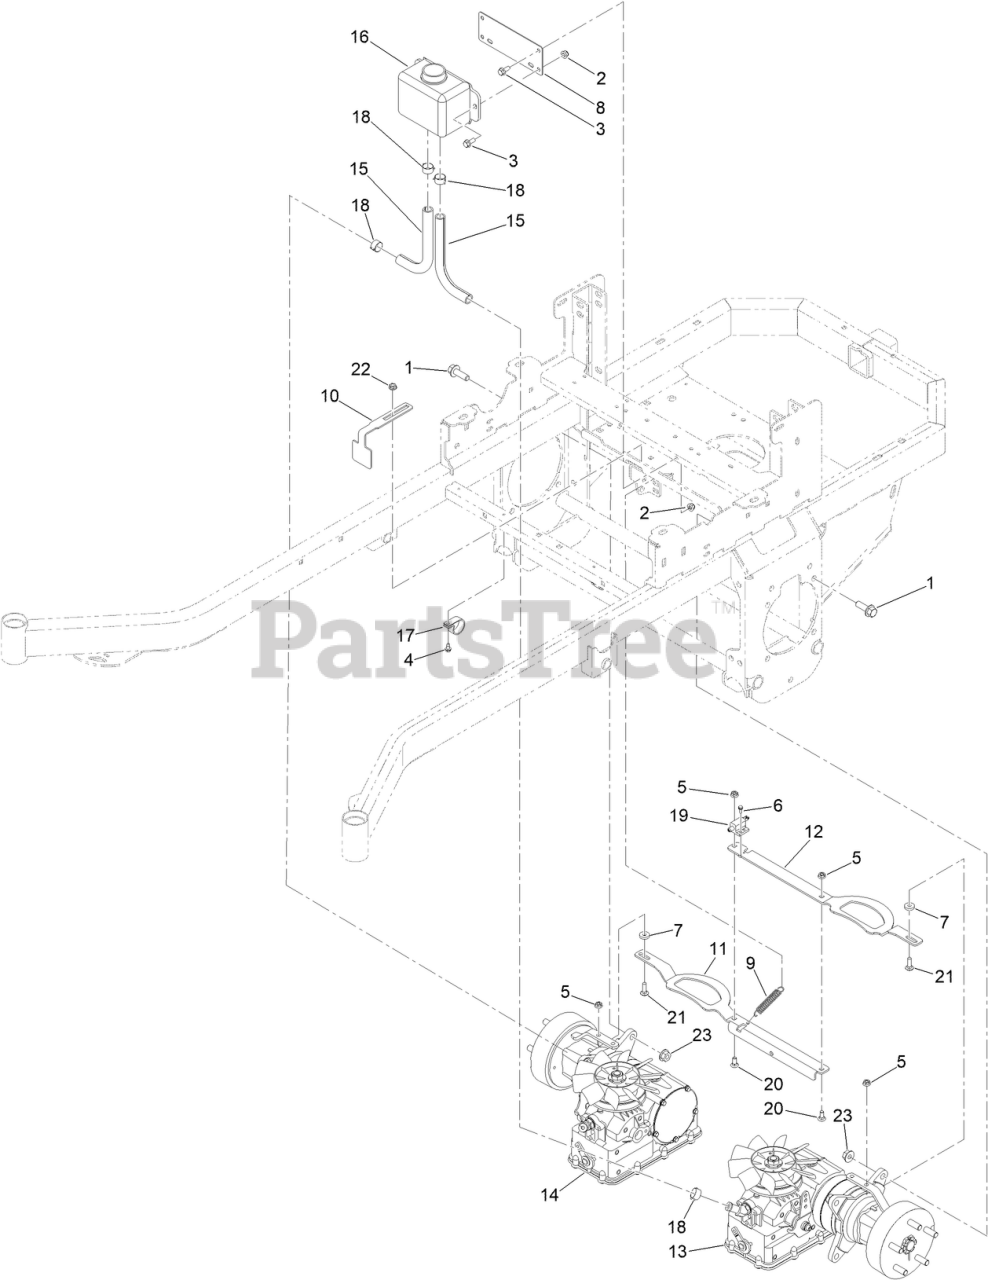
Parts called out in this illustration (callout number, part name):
1	SCREW-HHF
2	NUT-HF, NI
3	SCREW-HHF
4	SCREW-HWH
5	5/16-18 NYLON INSERT FLANGE L/NUT ZC
6	8-32 X 1/2 IND. HWH SLOT TYPE F TCS ZINC
7	.312 ID X .875OD X .1875 THK F/W NYL
8	HYDRAULIC RESERVOIR MTNG PLATE PAINT
9	MWR BRAKE PEDAL RELEASE SPRING
10	STAND TRANSM BRAKE INTERLOCK BRKT BLACK
11	KGZ PARK BRAKE BRKT RT PAINTED
12	KGZ PARK BRAKE BRKT LT PAINTED
13	HTG16 LT SIDE TRANSM W/CONTROL ORIFICE
14	HTG16 PARKER RT SD TRANS W/CNTRL ORIFICE
15	MWR 5/8IN HYDRAULIC HOSE, 1FT
16	HYDRAULIC FLUID RESERVOIR
17	1-1/4IN CUSHIONED LOOP CLAMP BLACK
18	22MM HOSE CLAMP (CTB-22ST-FK)
19	NO PLUNGER LIMIT SWITCH
20	BOLT-CARR
21	BOLT-CARR
23	NUT-HHF
